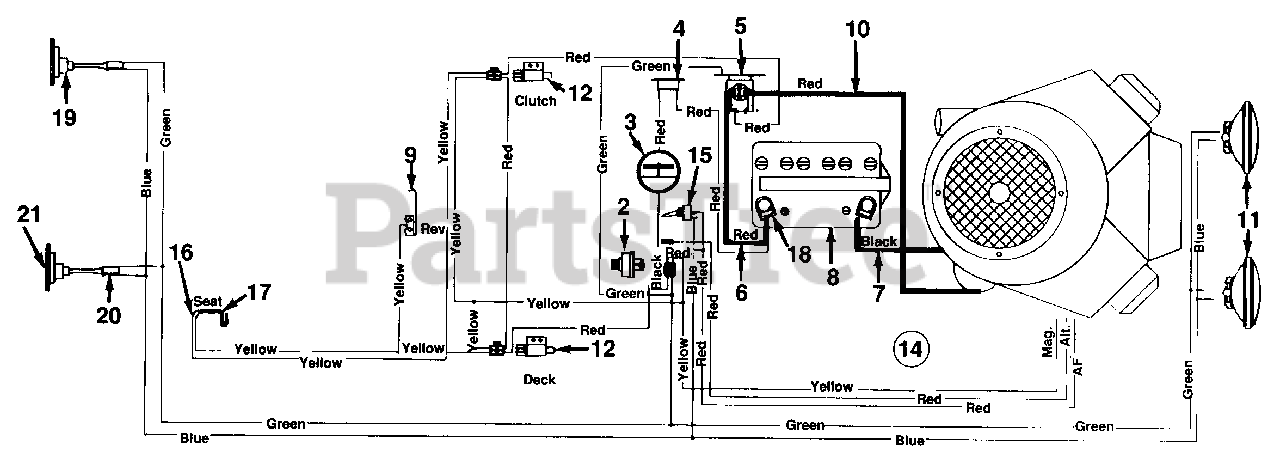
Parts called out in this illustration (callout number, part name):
2	Ignition Switch
3	Ammeter
4	Circuit Breaker 20 Amp
5	Solenoid
6	Electric Wire
7	Electric Wire
8	Battery
9	Spring Switch (Reverse Safety)
10	Electric Wire
11	Headlights
12	Safety Switch (PTO & Clutch)
14	Wire Harness
15	Light Switch
16	Safety Switch (Seat)
17	Safety Switch (Seat)
18	Battery Boot
19	Tail light
20	Tail light Harness
21	Tail light Bulb
